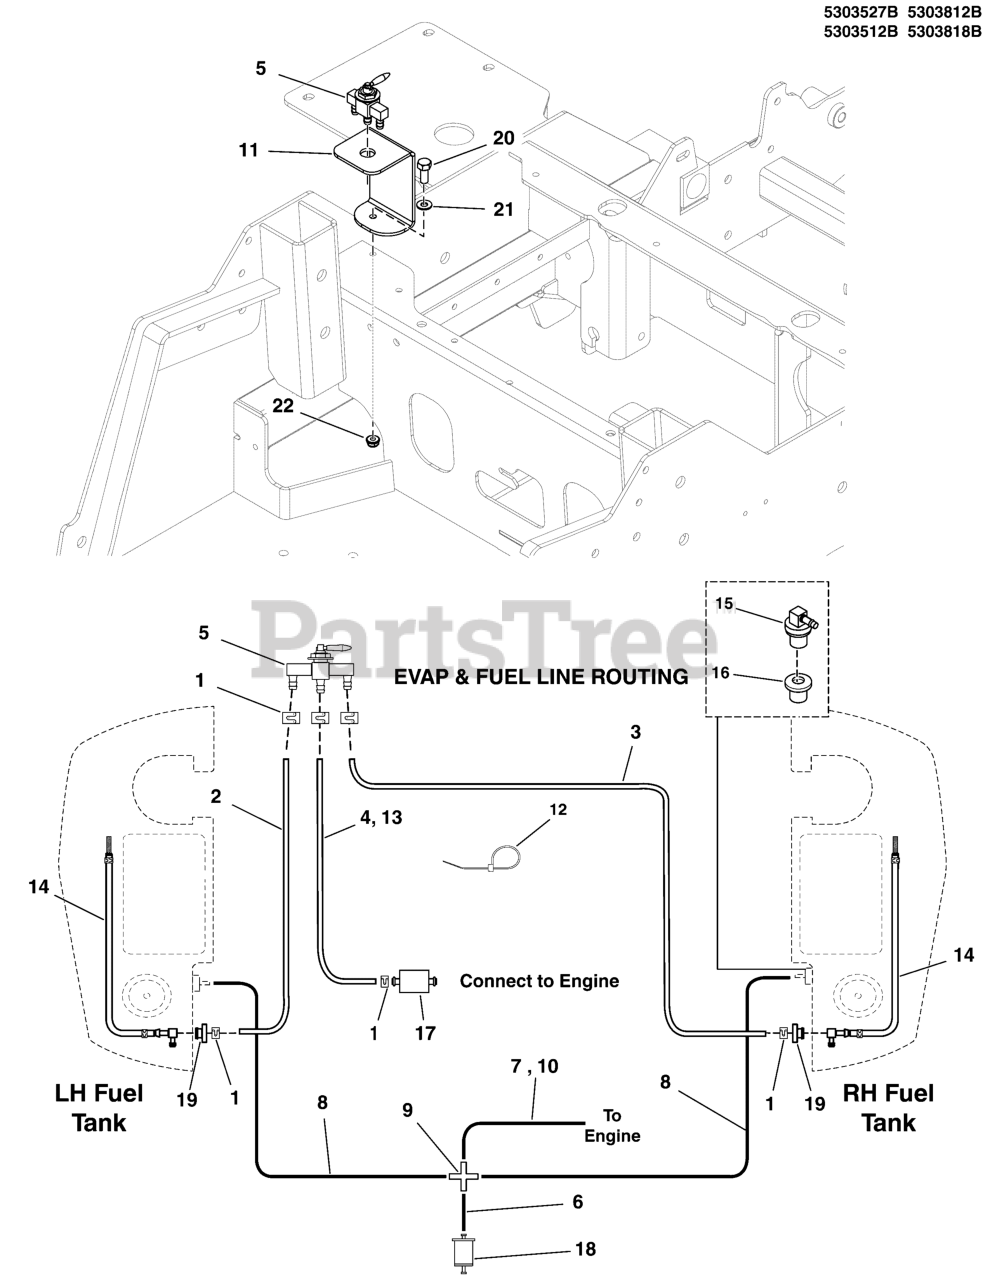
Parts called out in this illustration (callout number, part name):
1	CLAMP, Hose
2	1/4" Fuel Line, 11" Long
3	HOSE, 1/4" FUEL, 27.00"
4	1/4" Fuel Line, 22" Long
5	VALVE, FUEL STRAIGHT, OUTLET
6	HOSE, VAPOR, 5MM ID, 3.00 LG
7	HOSE, VAPOR, 5MM ID, 37.00 LG
8	HOSE, VAPOR, 5MM ID, 23.00 LG
9	FITTING, BARBED CROSS, 3/16" BLK NYLON
10	HOSE, VAPOR, 5MM ID, 17.00 LG
11	MOUNT, FUEL VALVE, 2100Z - BLK
12	TIE, SELF-LOCKING, 6"
13	HOSE, FUEL, 1/4 IN, LW PRMTN, 16" LONG
14	PICKUP TUBE ASSEMBLY, FUEL LINE (SV)
15	REMOTE VENT ASSEMBLY
16	GROMMET (SV)
17	FUEL FILTER (SV)
18	FILTER, FUEL
19	BUSHING-FUEL TANK RED RUBBER
20	BOLT, 5/16-18 X 3/4 GD5
21	WASHER, 5/16" SAE
22	NUT, 5/16-18 HEX NYLOCK FLANGE NUT
